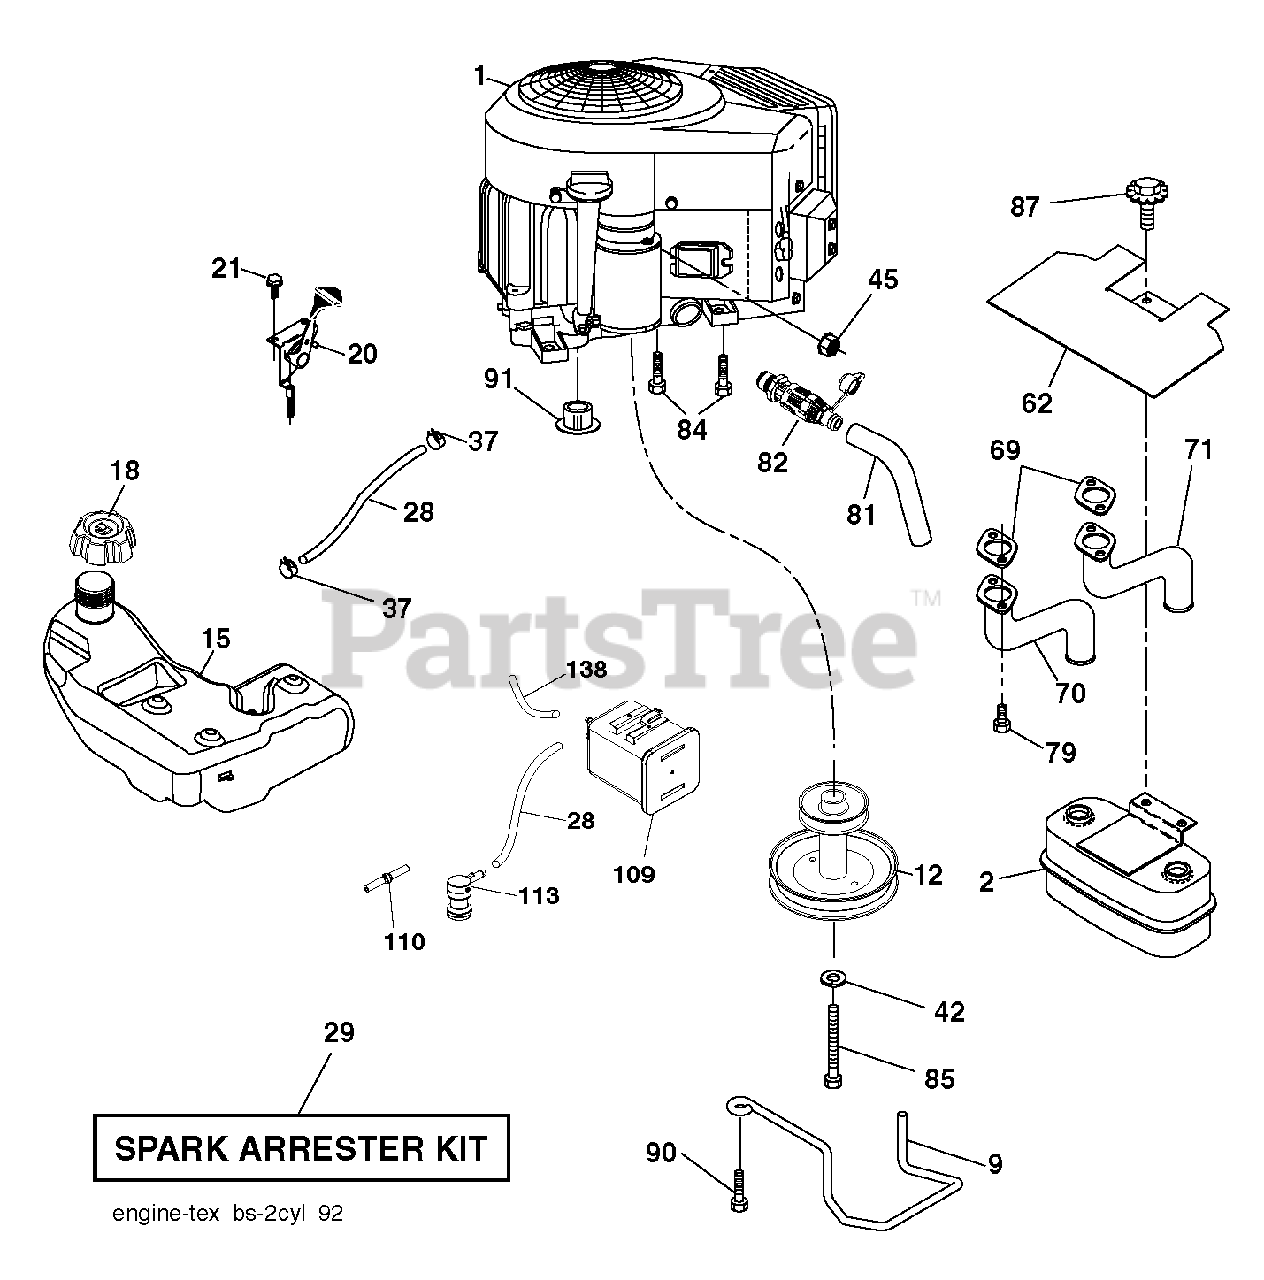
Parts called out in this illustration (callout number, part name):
2	MUFFLER.ASM.TWN.EXTNDED.DFLCTR
9	KEEPER BELT ENGINE
12	PULLEY ENGINE
15	TANK ASM.FUEL.3
18	CAP.ASM.FL.RITCH.3"E10.SYM.498
20	CONTROL.TH/CK.COBRA.B&S.TWN.
21	SCREW.#10 X 0.750.BOS
28	LINE.FUEL.64"REAR.EMIS
29	KIT.SPARK ARRESTOR 794945 B&S
37	HOSE CLAMP
42	LOCKWASHER
45	NUT
62	SHIELD.HEAT.MUFFLER
69	GASKET.MUFFLER
70	EXHAUST.TUBE.LH.BS/TWIN
71	EXHAUST.TUBE.RH.B&S.TWIN.INTEK
79	SCREW.SOCKET.HEAD.5/16-18
81	TUBE, DRAIN OIL ASM.
82	VALUE.OIL.DRAIN
84	SCREW.3/8-16
85	BOLT HEX 7/16-20X4-1/4"
87	Bolt, 5/16-18 X 1-3/4
90	SCREW 3/8-16X1
91	BUSHING.1.375OD
109	CANNISTER, CARBON
110	VALVE.ASM.ANTI-SLOSH
113	VALVE.SLANT.CARTRDG.90 DEG.TEX
138	RP PURGE LINE
